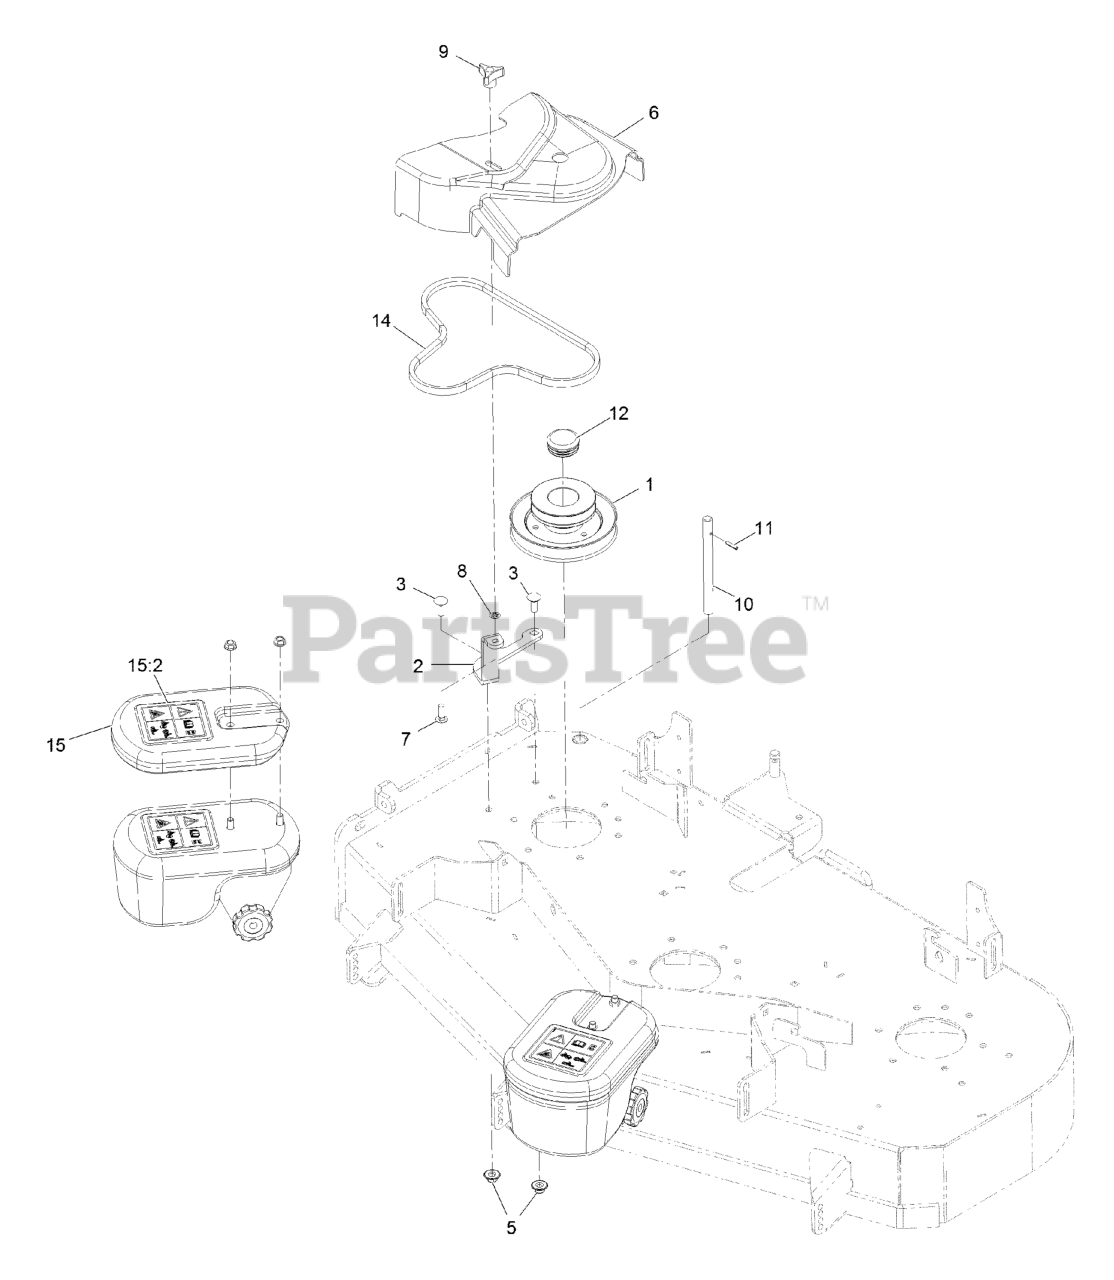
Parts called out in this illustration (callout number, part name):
1	JACKSHAFT-UV DRIVE, 484 S
2	BRACKET, SMALL UV BELT CO
3	BOLT-CARR
5	Nut-Nyloc 3/8-16 Flg
6	COVER-BELT, UV 48
7	BOLT-CARR
8	RING-RETAINING, BOLT
9	KNOB-3 PRONG
10	SHAFT-CATCHER, GRASS
11	PIN-ROLL
12	PLUG-ROUND PLASTIC
14	BELT-BLOWER
15:2	DECAL-WARNING, TRACTION
